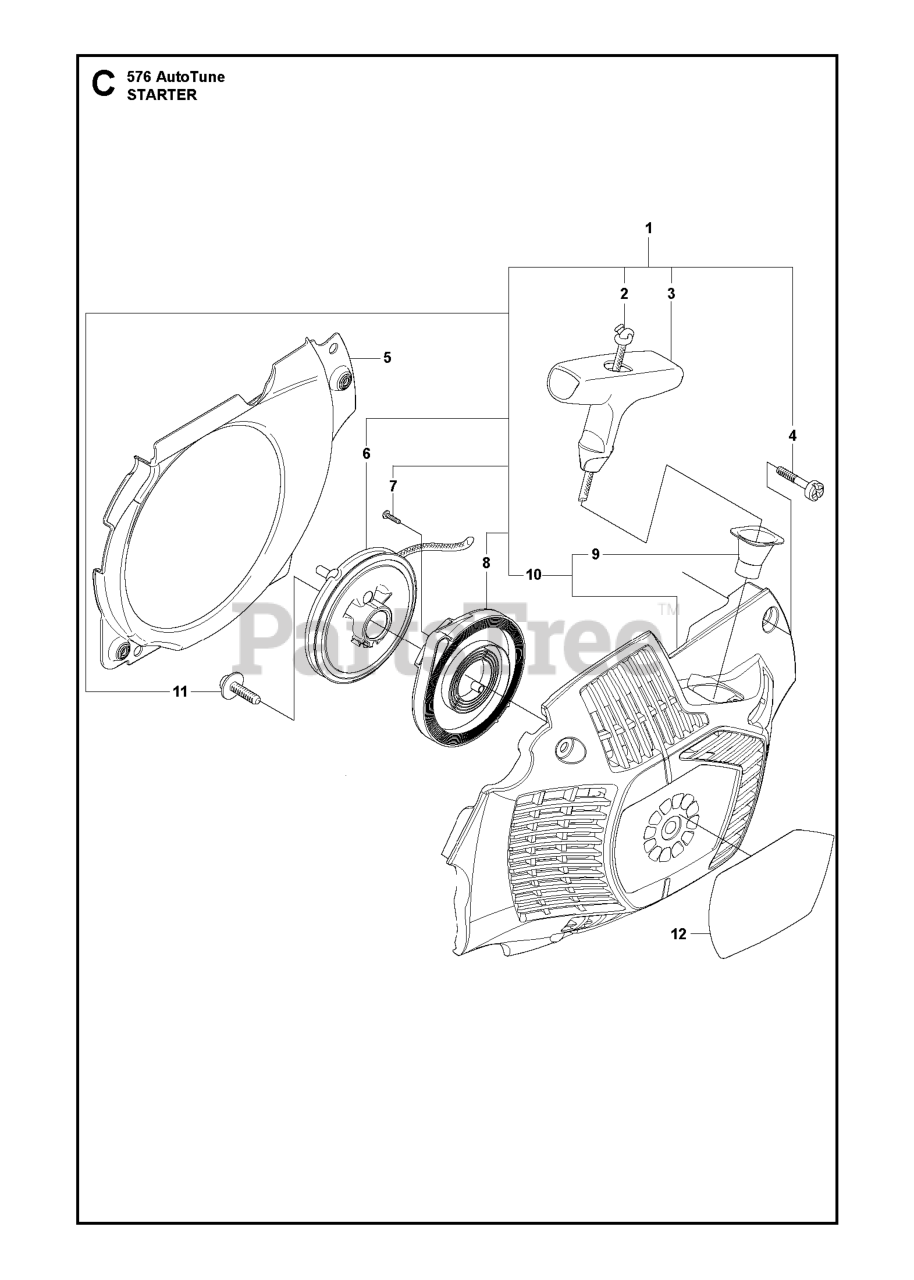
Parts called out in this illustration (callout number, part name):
1	STARTER ASSY
2	STARTER ROPE
4	SCREW.CIHPANMO M5X19 10.9
6	STARTER PULLEY
8	SPRING
10	STARTER HOUSING
12	LABEL
12	LABEL (576XPG AUTO TUNE)
